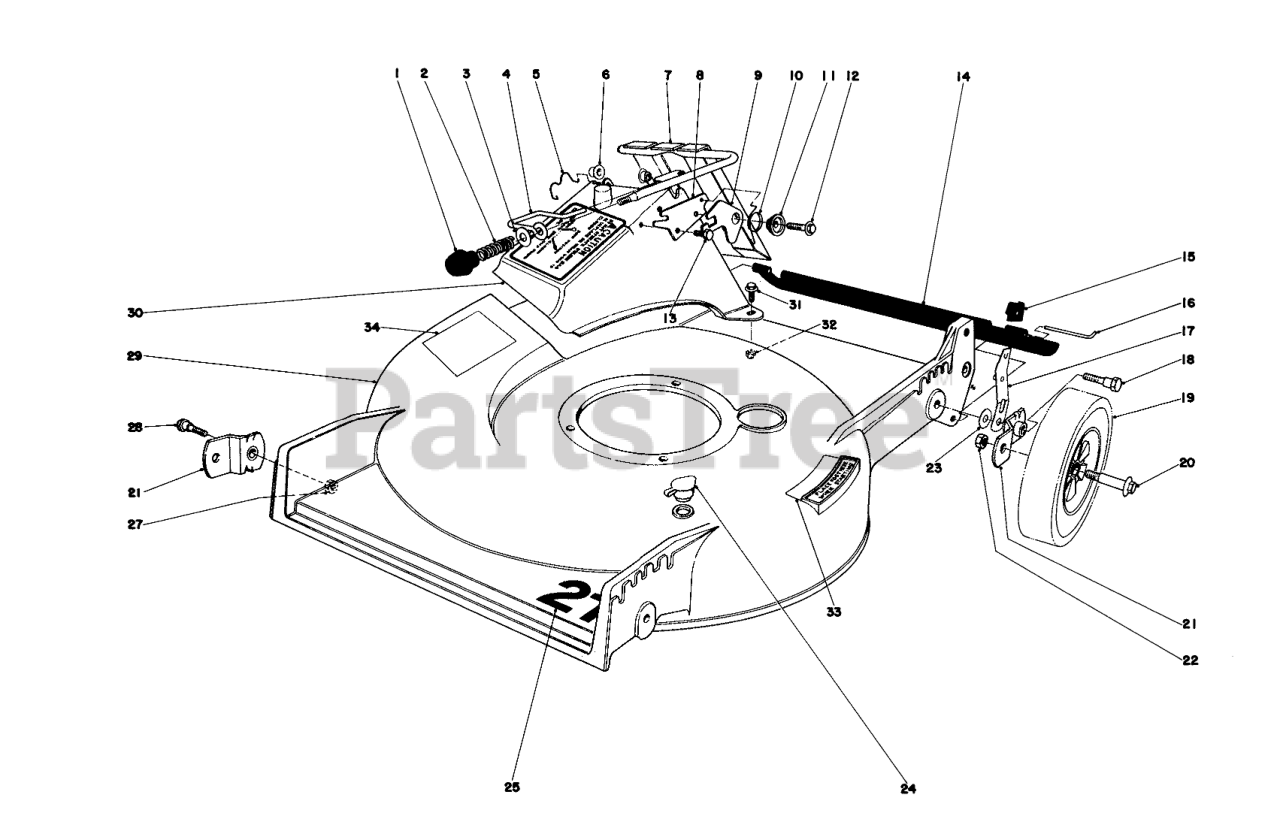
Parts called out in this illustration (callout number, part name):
2	COMPRESSION SPRING
3	WASHER
4	DOOR LATCH
5	DOOR RETAINER
6	BUSHING-NYLON
7	DOOR & HANDLE WA
8	DOOR LATCH PLATE
9	Latch Safety
10	TORSION SPRING
11	Latch Spacer
12	Screw
13	SCREW-HWH
14	SHIELD - TRAILING
15	KNOB-ARM
16	Rod Shield
17	SPRING ARM ASM (R&S)
18	5/16-18 PIVOT SCREW
19	WHEEL & TIRE ASM
20	BOLT-WHEEL
21	PIVOT ARM ASM A
22	Nut
23	WASHER-PIVOT
24	WASHOUT PLUG
25	Decal 21"
27	Nut
28	PIVOT SCREW
29	Deck
30	DISCHARGE CHUTE B
31	SCREW-HH
32	NUT-LOCK, NI
33	Decal Place Foot Here
34	Decal Caution
